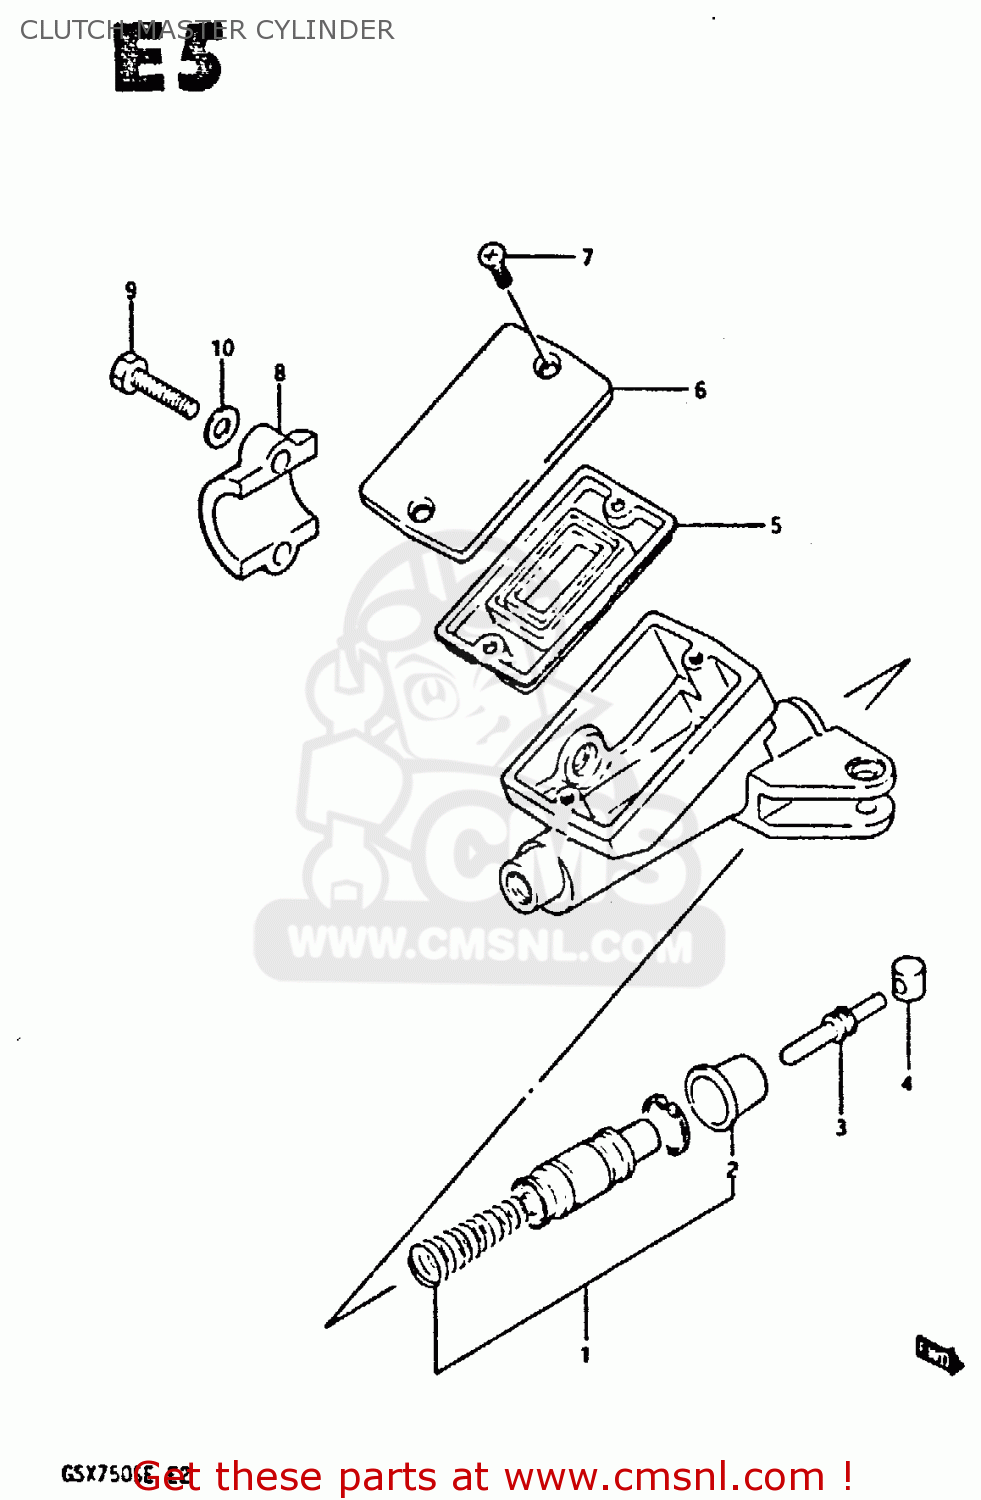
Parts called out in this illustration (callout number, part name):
1	PISTON & CUP SET
2	BOOT
3	ROD,PUSH
4	BUSH
5	6
6	CAP
7	SCREW
8	HOLDER,MASTER CYLINDER
9	BOLT
10	WASHER
